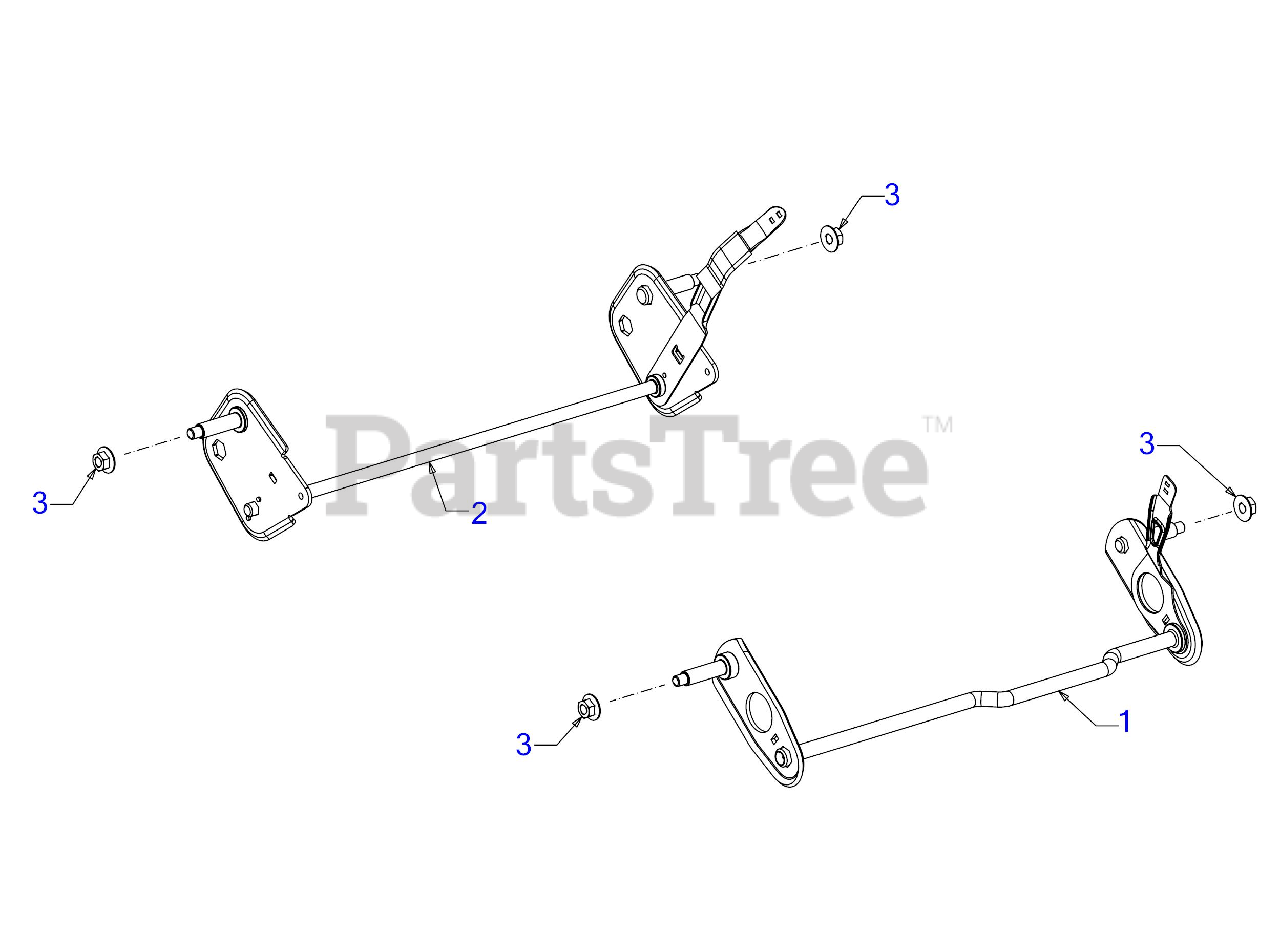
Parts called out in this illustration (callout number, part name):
1	FRONT AXLE ASSEMBLY
2	REAR AXLE ASSEMBLY
3	FLANGE LOCK NUT
